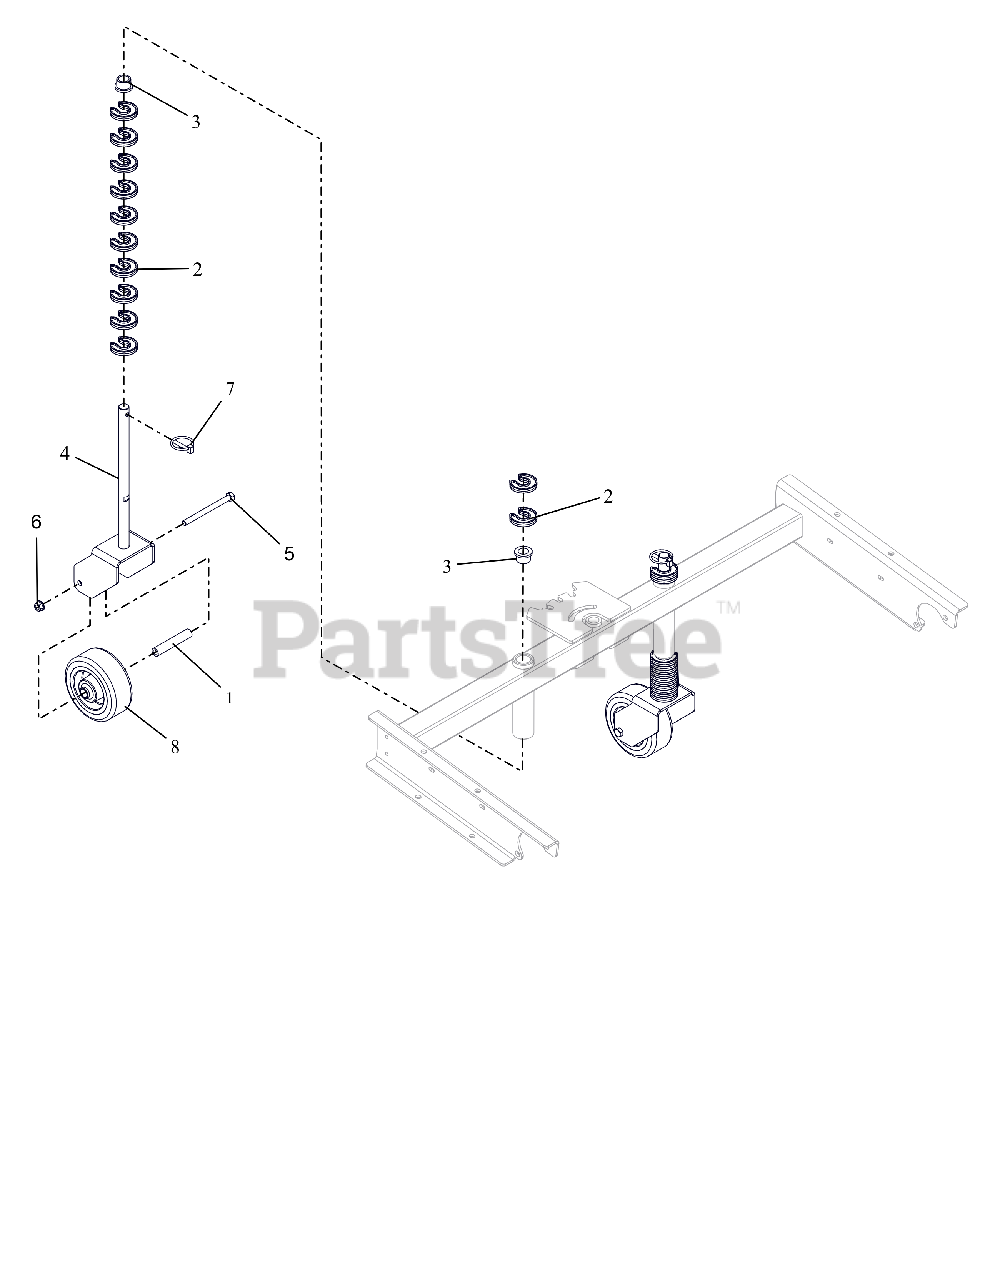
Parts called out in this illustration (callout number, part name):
1	SPACER, CASTER WHEEL
2	CLIP-HOC FIXED
3	BUSHING, FLANGE .75X.75X1.0
4	FORK, CASTER
5	BLT, HEX 0.375-16X4.5 GR5 ZCC
6	NUT-LK-TOP-FLG .38-16 ZC120
7	PIN, 1/4X1-9/16 LYNCH
8	WHEEL, CASTER - 5"OD
